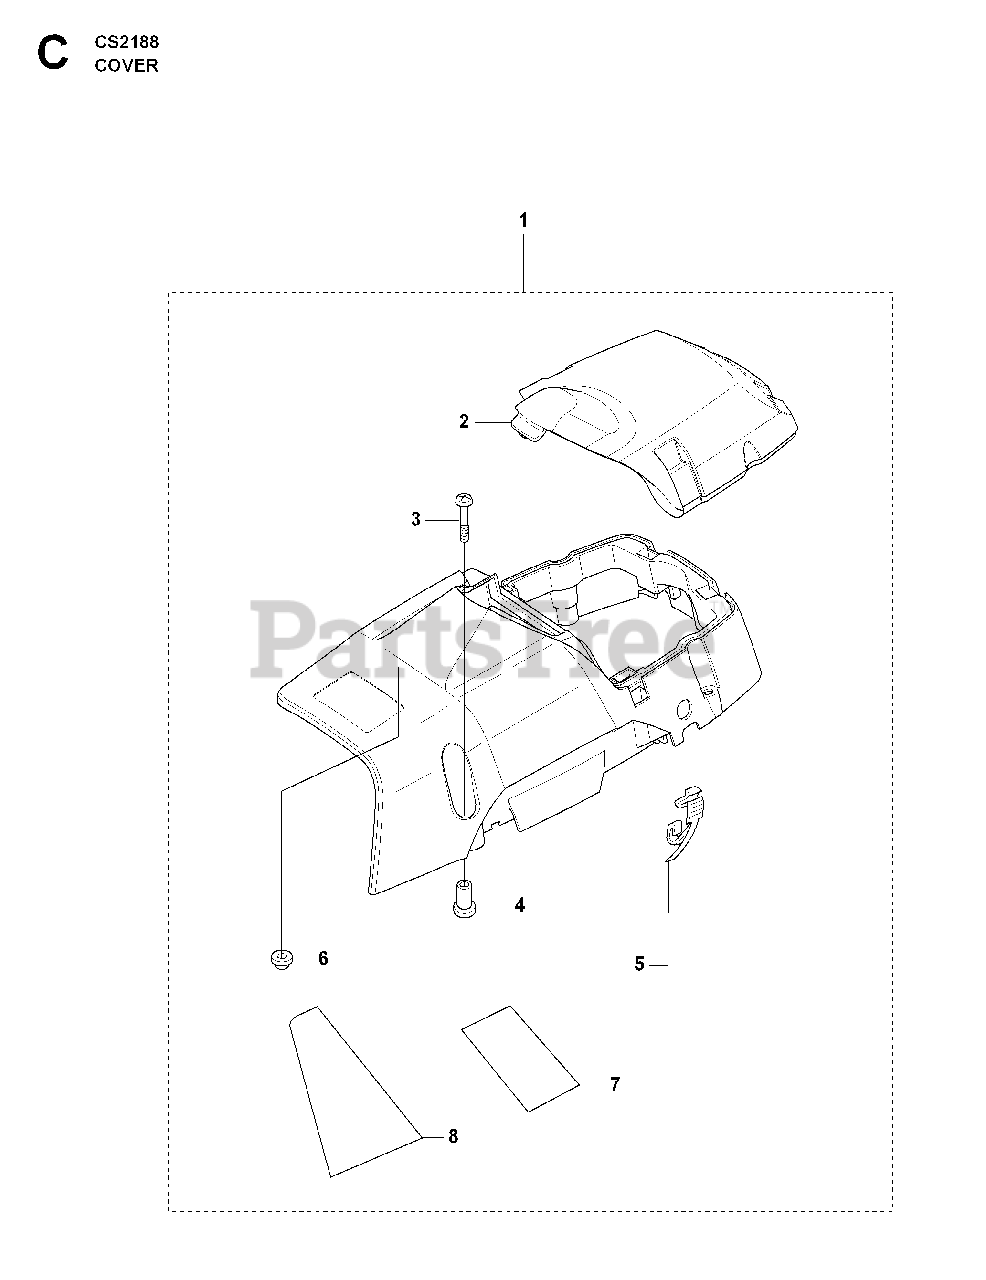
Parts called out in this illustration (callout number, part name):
1	CYLINDER COVER
2	COVER
3	SCREW
4	SLEEVE
5	CLIP
6	GROMMET
